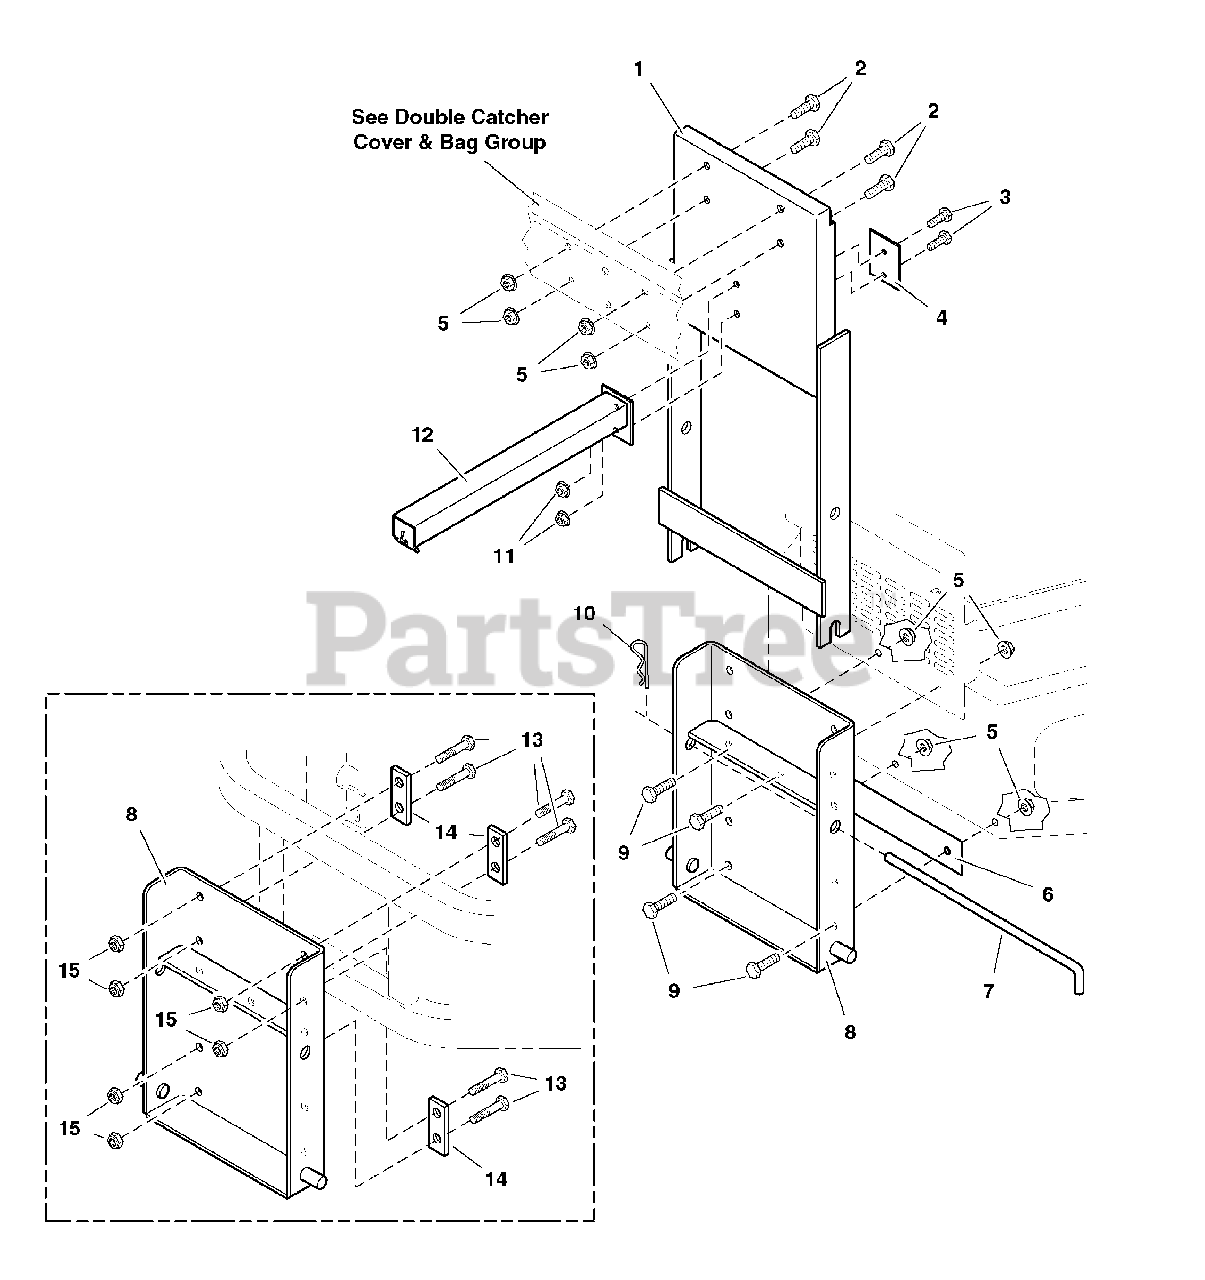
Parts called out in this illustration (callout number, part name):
1	COVER SUPPORT ASSEMBLY
2	BOLT, 3/8-16 x 3/4
3	BOLT, 5/16-18 X 3/4 GD5
4	REINFORCEMENT PLATE
5	NUT, 3/8-16 Hex Serrated Flange
6	BUMPER SPACER
7	SUPPORT ROD
8	BUMPER MOUNT PLATE
9	BOLT, 3/8-16 x 1
10	HAIRPIN CLIP
11	NUT, 5/16-18 HEX SERRATED FLANGE (LARGE)
12	COVER LATCH ARM
13	BOLT, 3/8-16 x 2-1/2
14	CLAMP, Bar
15	NUT, 3/8-16 Hex Nylon Lock
